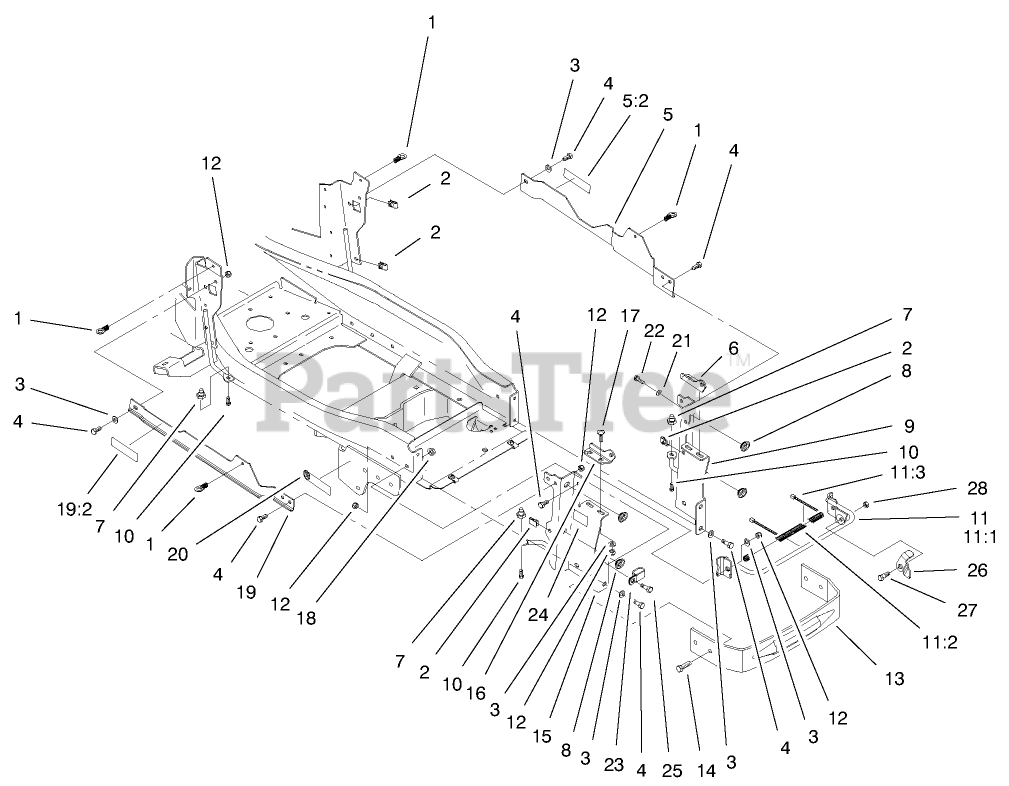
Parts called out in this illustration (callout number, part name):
1	LATCH ASM
3	WASHER-PLAIN
4	SCREW-HH
5	SUPPORT ASM
5	SUPPORT / DECAL ASM
5:2	DECAL-WARNING
5:2	DECAL - WARNING
6	BRACKET-HINGE, LOWER LH
7	MOUNT-SIDEPANEL
8	GROMMET
10	SCREW-PLASTITE
11:2	COVER-BRACE
11:3	TIE-CABLE
12	NUT-LOCK, NI
14	SCREW-HH
15	SUPPORT-HOOD, RH
16	BRACKET-HINGE, LOWER RH
17	SCREW-CARR
18	NUT-LOCK, NI
19	SUPPORT ASM
19:2	DECAL - WARNING
19:2	DECAL-WARNING
20	DECAL-ATTACH A-MATIC
21	WASHER-FLAT
22	SCREW-THD FORM, HWH
23	CLAMP-TUBE
24	DECAL-SURFACE, HOT
25	SCREW-HH
26	LEVER-PROP, HOOD
27	BOLT-SHOULDER,HFH
28	NUT-LOCK, NI
